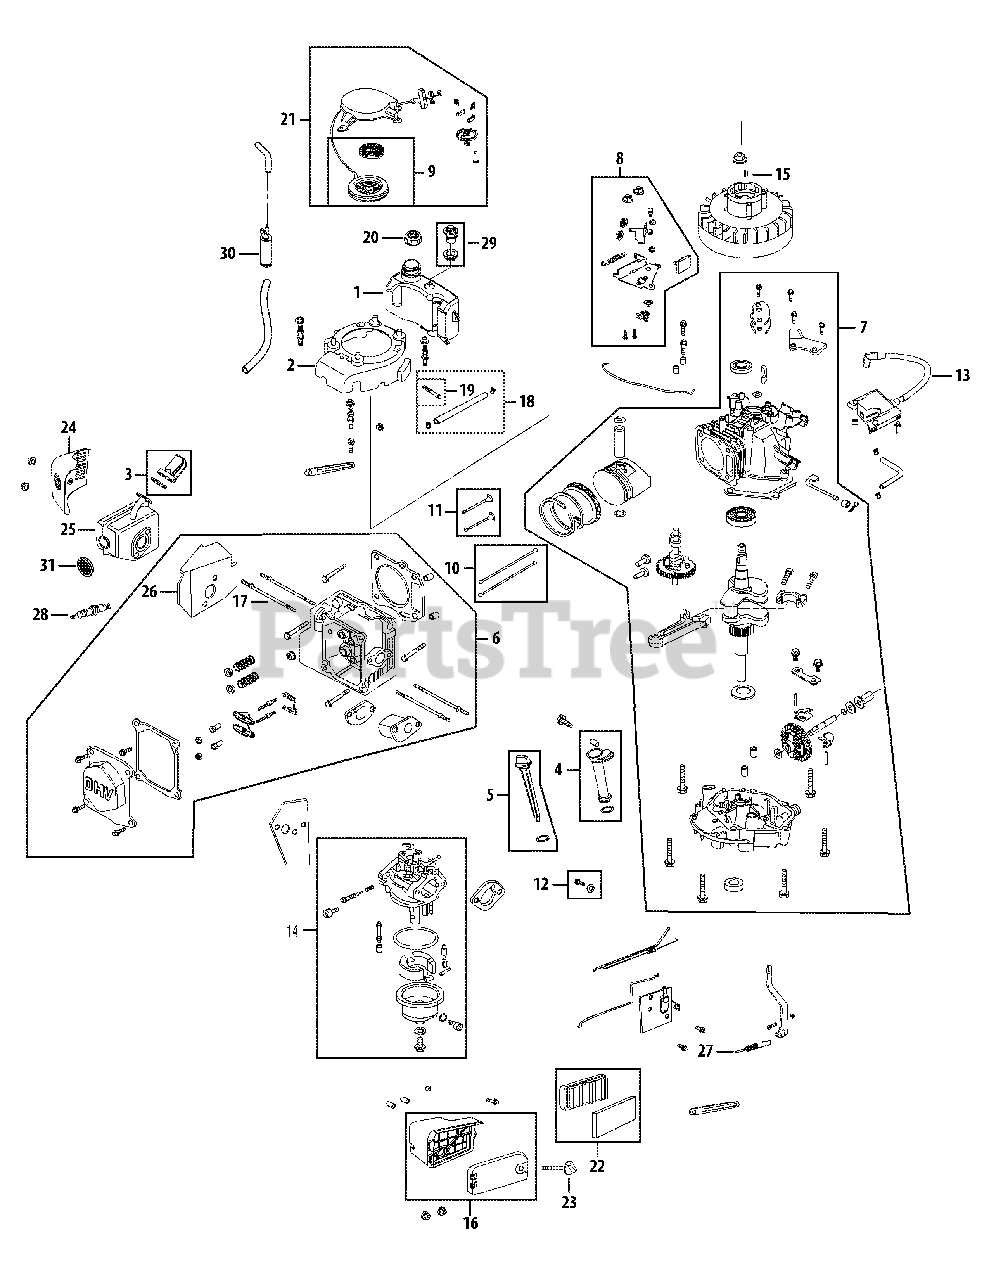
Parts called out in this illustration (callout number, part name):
1	Fuel Tank
2	Flywheel Shroud
3	Reed Valve Assembly
4	Oil Filler Tube Assembly
5	Dipstick Assembly
6	Cylinder Head Assembly
7	Short Block Assembly
8	Stop Switch and Brake Assembly
9	Recoil Spring and Pulley Assembly
10	Push Rod Kit
11	Valve Kit
12	Oil Drain Plug and Washer Assembly
13	Ignition Coil
14	Carburetor Assembly
15	Flywheel Key
16	Air Cleaner Housing Assembly Complete
17	Muffler Stud Assembly
18	Fuel Line Kit
19	Fuel Filter
20	Fuel Cap
21	Recoil Starter Assembly
22	Air Cleaner Kit
23	Air Cleaner Thumb Screw
24	Muffler Guard
25	Muffler
26	Muffler Gasket/ Heat Shield
27	Governor Return Spring
28	Spark Plug
29	Roll Over Valve Assembly
30	Carbon Cannister
31	Spark Arrestor
